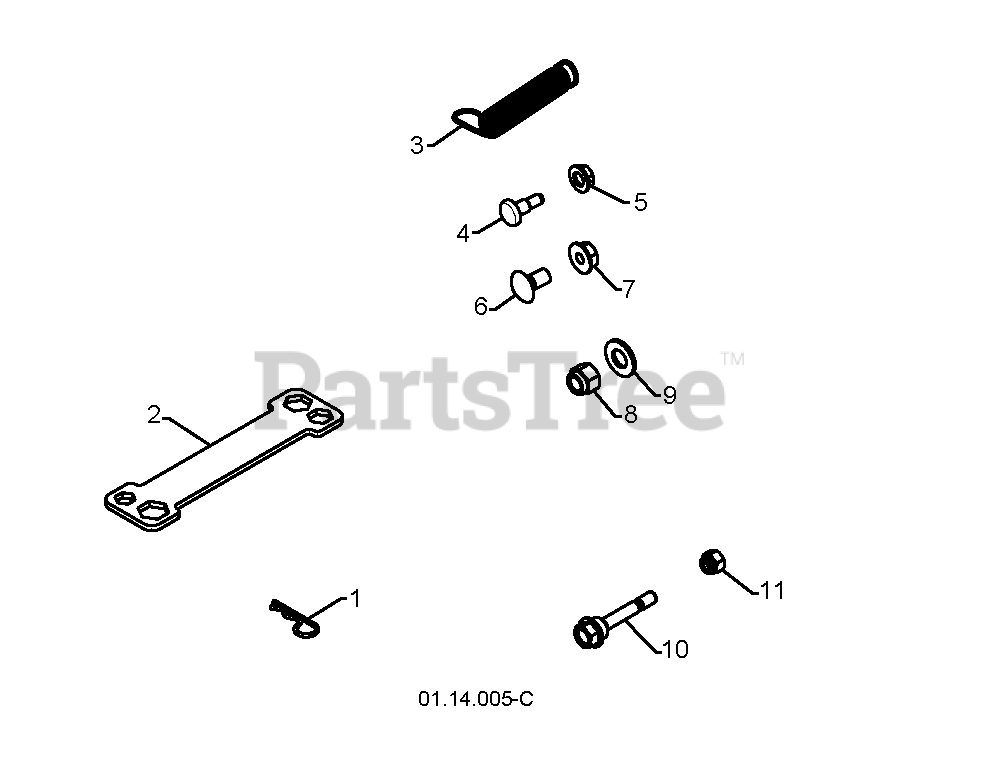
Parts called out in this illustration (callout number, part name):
1	SPRING RETAINER
2	RP WRENCH, SNOWTHROWER
4	BOLT, SHOULDER
5	NUT.HEX.FLANGE.1/4
6	BOLT
7	NUT, LOCK 5/16-18
8	NUT
10	BOLT, SHOULDER SHEAR
11	LOCKNUT
